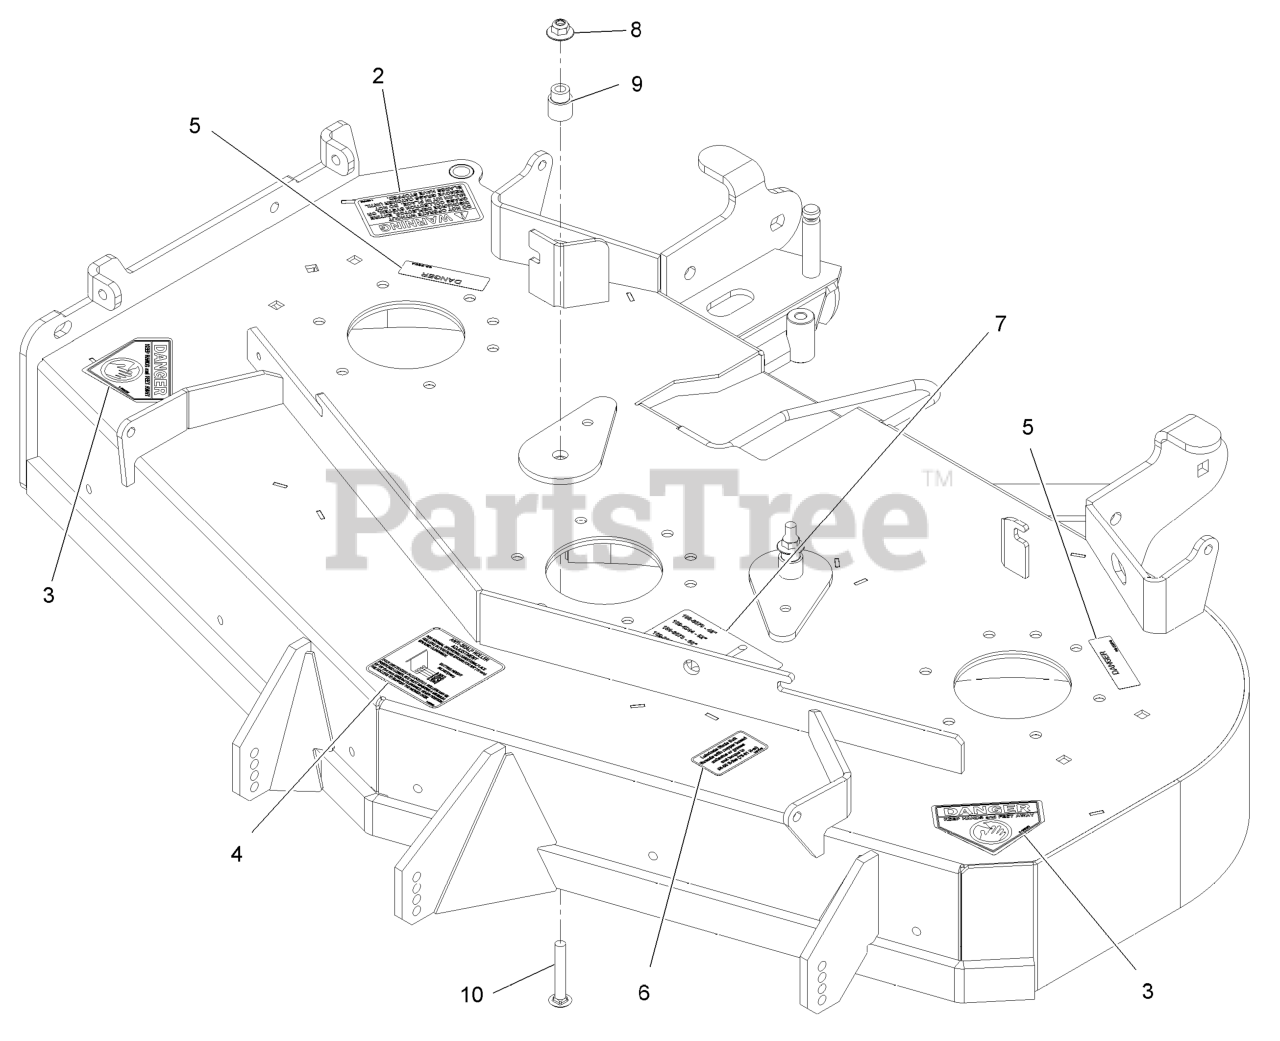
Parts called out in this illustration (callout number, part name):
2	DECAL-WARNING, DISCHARGE
3	DECAL-DANGER
4	DECAL,ANTISCALP
5	DECAL-COVER, MISSING
6	DECAL,BOLT TORQUE
7	DECAL,BELT ROUTING
8	Nut-Nyloc 3/8-16 Flg
9	BUSHING-IDLER
10	SCREW-CARR
